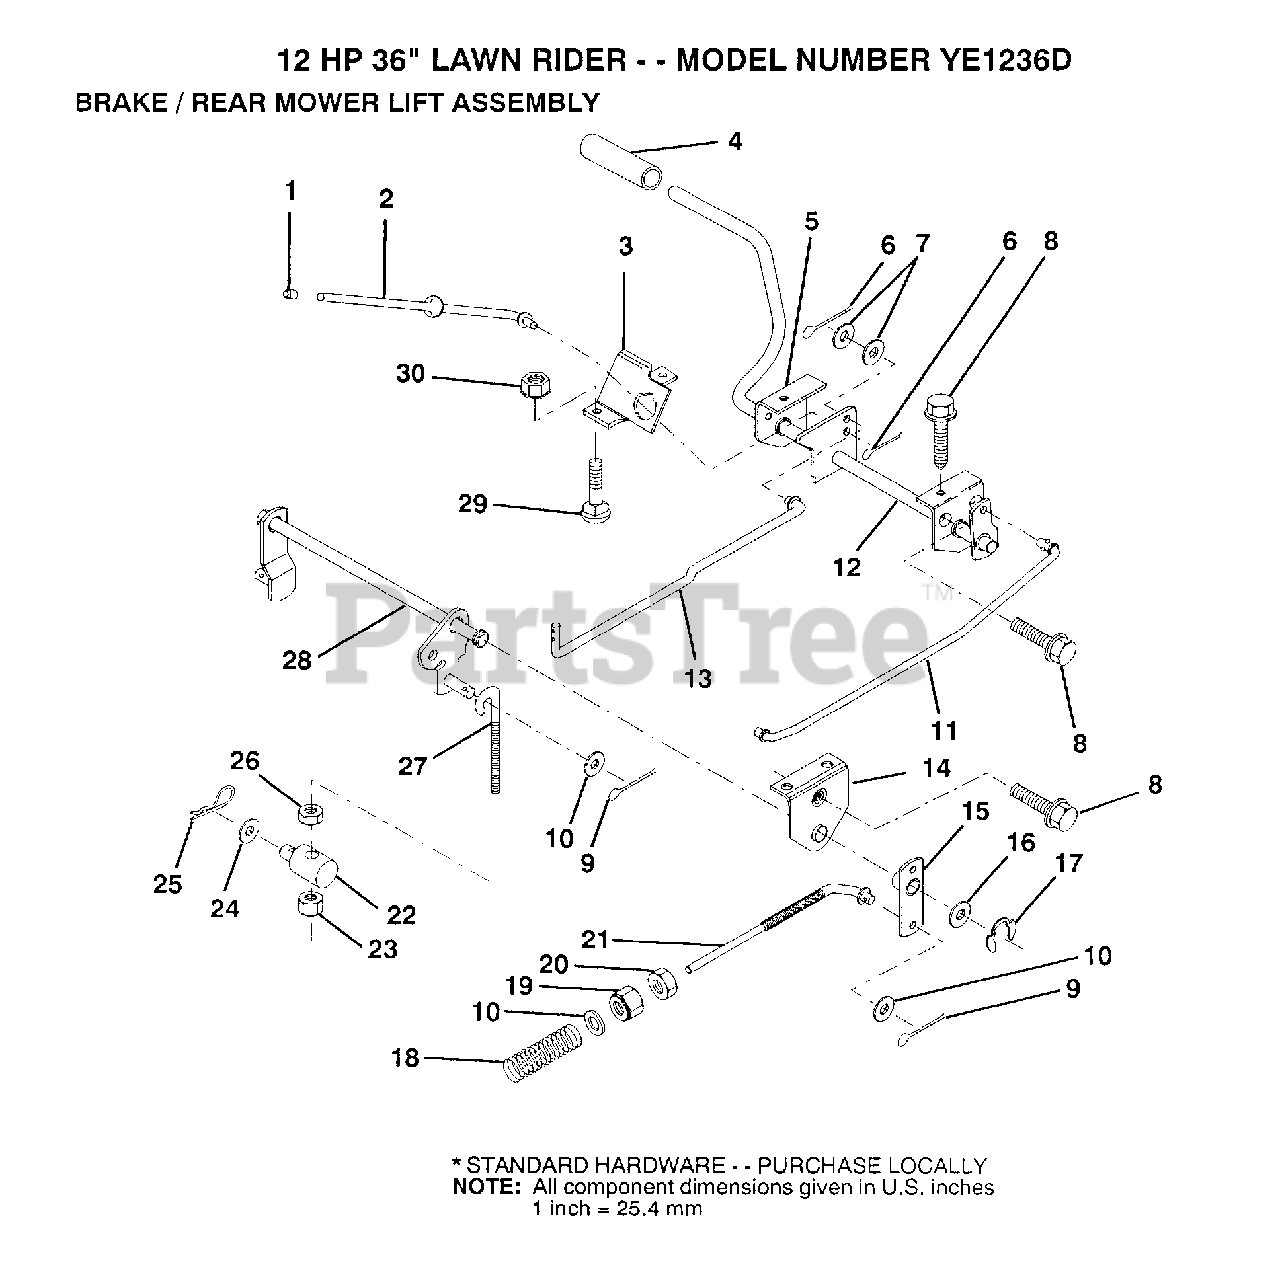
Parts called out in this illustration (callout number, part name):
1	PLUNGER CAP T
2	"ROD,PARK BRAKE"
3	"BRKT,PARK BRAKE"
4	PEDAL COVER T
5	"BRKT,CLU PEDAL LH"
7	WASHER
8	SCREW LT
9	COTTER PIN
10	WASHER
13	"ROD,CLUTCH"
14	"BRKT,LIFT SHAFT"
15	PVT BRAKE ARM ASM
16	WASHER T
17	KLIP RING
18	SPRING ROD LT
20	NUT
24	WASHER
25	SPRING.RETAINER
26	LOCKNUT
27	"LINK, MOWER REAR"
